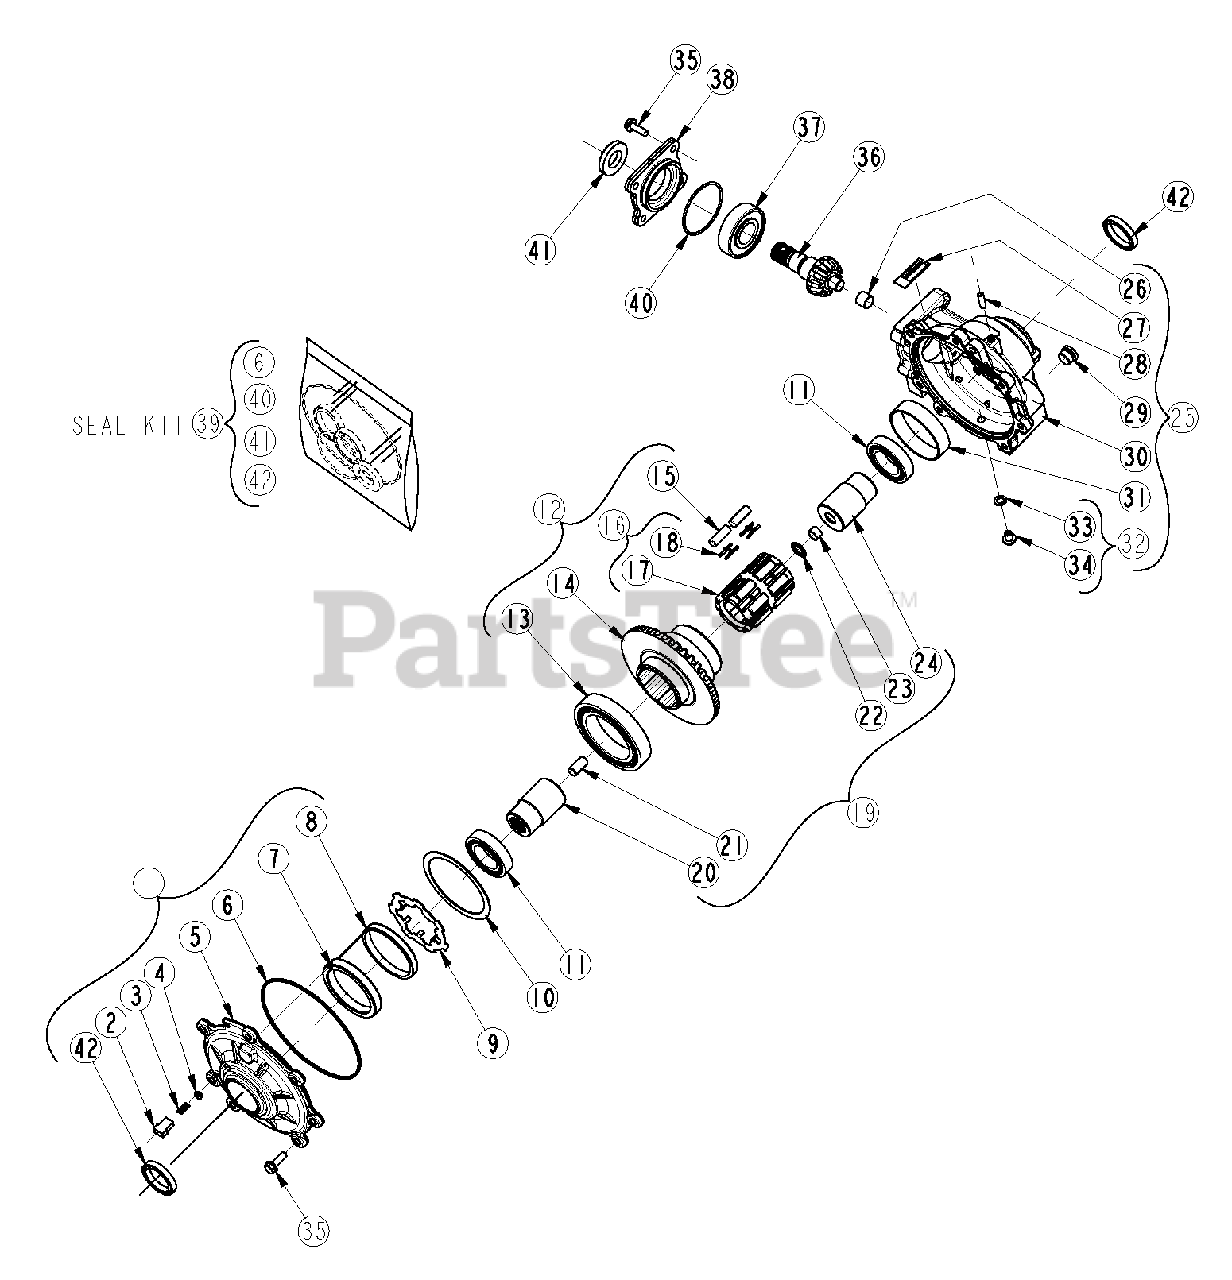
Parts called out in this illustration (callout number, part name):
1	OUTPUT COVER PLATE ASSEMBLY #1 Kit (Includes 2 – 8 & 42)
9	ARMATURE PLATE
10	SHIM .05 THICK BRASS, HALF HARD
11	6008-C3 DEEP GROOVE ROLLER BEARING
12	CLUTCH ASSEMBLY #12 Kit (Includes 13 – 16)
13	6015-C3 DEEP GROVE ROLLER BALL BEARING (Sold separately & with #12 Kit)
14	CLTH.HSG./RNG GR., 42T 6.75DP (with #12 Kit) Not serviced, replaced by 6203-9U-088, Item 43
15	ROLL KIT (Sold separately & with #12 Kit)
16	ROLL CAGE ASSEMBLY #16 Kit (Includes 17 & 18)
18	SPRING KIT, H-CLIP .008 THK (Sold separately & with #16 Kit)
19	RACE/OUTPUT HUB ASSEMBLY #19 Kit (Includes 20 & 21)
21	PERMIGLIDE BUSHING (Sold with #19 Kit)
22	TC815 NEEDLE ROLLER THRUST BEARING (Sold separately & with #19 Kit)
23	1/2 DIA X 1 LG. DOWEL PIN (Sold separately & with #19 Kit)
25	GEARCASE ASSEMBLY #25 Kit (Includes 26 – 32)
26	DU BUSHING (Sold with #25 Kit)
29	PLUG OIL FILL 3/4-16 HOLLOW HEAD (Sold separately & with #25 Kit) Torque Item 29 (PLUG OIL FILL 3/4-16 HOLLOW HD) Tighten to 10
32	DRAIN PLUG ASSEMBLY #32 Kit (Includes 33 & 34)
35	BOLT KIT Torque Item 35 (5/16" X 1" Hex Head Bolts) Tighten to17 ft-bs
36	SHAFT PNION 11T3.75DP, MACHINED, Not serviced, replaced by 6203-9U-088
37	6306-03-C3 DP GROOVE ROLLER BALL BEARING
38	COVER PLATE, INPUT-MACHINED
39	MINOR REPAIR KIT #39 Kit (Includes 6 & 40 – 42)
41	TRIPLE LIP OIL SEAL (Sold with #1 Kit & #39 Kit)
42	OIL SEAL, OUTPUT (Sold with #39 Kit)
43	KIT-GEAR, HARD TURNED (Includes 14 & 36)
